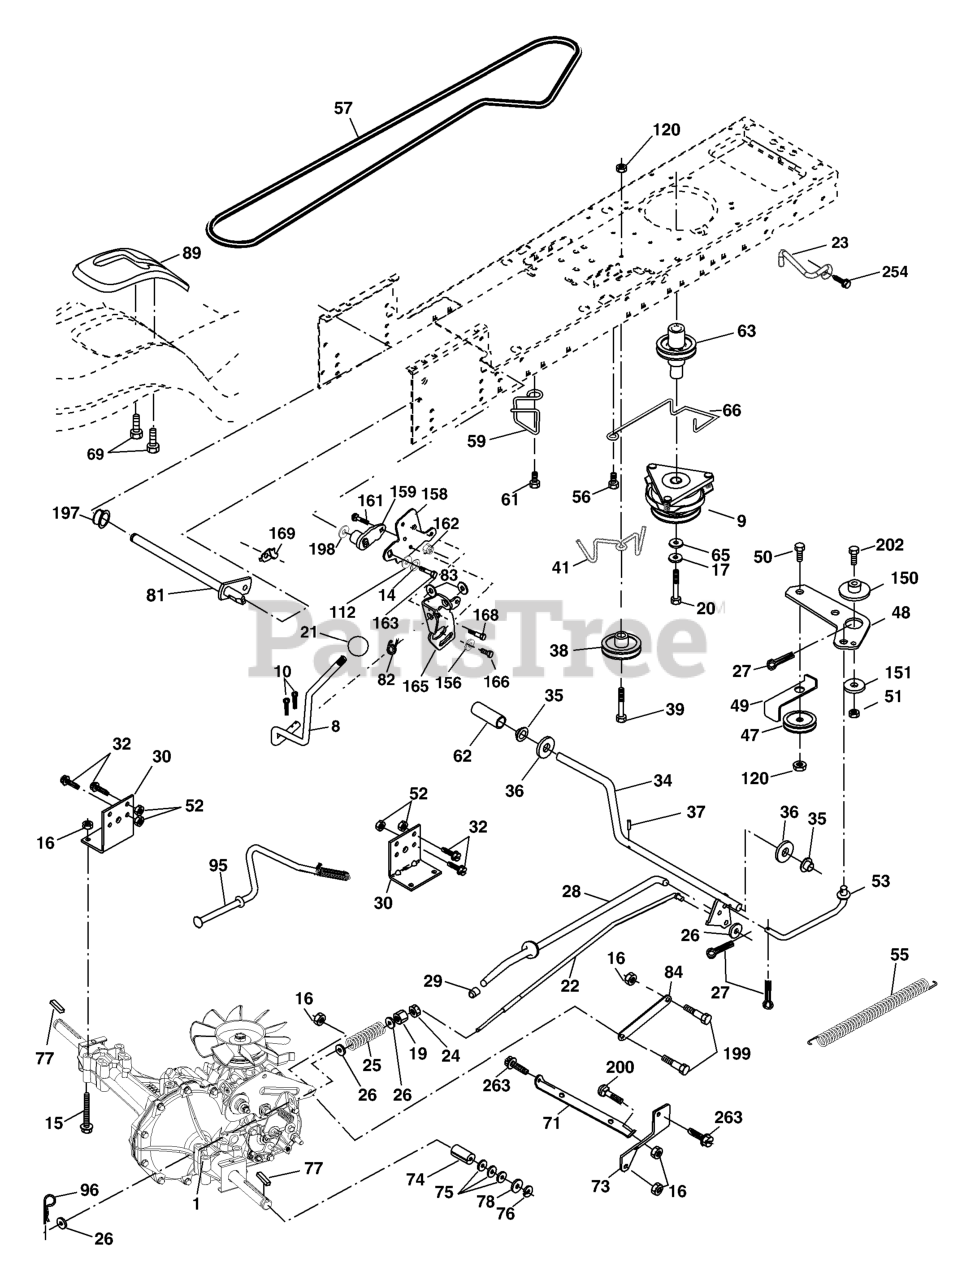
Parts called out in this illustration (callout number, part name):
8	ROD SHIFT FENDER ADJUST STLT
9	CLUTCH, ELECTRIC
10	PIN COTTER
14	LOCKWASHER
15	BOLT HEX 5/16-18 GR 5
16	NUT.71038.31-18.HEX.NYLOCK
19	NUT
20	BOLT HEX 7/16-20X4-1/4"
21	KNOB.DELUXE.(PISTOL.GRIP).BLAC
22	ROD BRAKE HYDRO
23	BRKT ASM MTNG
24	NUT
25	SPRING ROD LT
26	WASHER
27	COTTER PIN
28	ROD, PARKING BRAKE
29	PLUNGER CAP
30	BRKT, TRNSXLE MNT 20"
32	BOLT
34	SHAFT, FOOT PEDAL
35	BEARING.NYLON
36	WASHER LT
37	DRIVE PIN
38	PULLEY IDLER COMPOSITE
41	KEEPER, BELT IDLER
47	IDLER PULLEY
48	BELLCRANK, CLUTCH
49	RETAIN BELT
50	BOLT.3/8-16X1.50
52	LOCKNUT
53	LINK, CLUTCH LT
55	SPRING, RETURN LT
56	SCREW.3/8-16
57	DRIVE BELT, LTH & YTH TRACTORS
59	KEEPER, BELT CENTER
61	SCREW 3/8-16X.875
62	PEDAL COVER T
63	PULLEY, ELEC CLUTCH
65	LOCKWASHER
66	KEEPER BELT ENGINE
69	SCREW.HI-LO.CONSOLE
71	STRAP TORQUE LH HYDRO
73	STRAP TORQUE RH HYDRO
74	SPACER AXLE
77	SQUARE KEY
81	SHAFT ASM CROSS TAPERED
82	SHIFT SPRING
83	WASHER
84	LINK TRANSAXLE
89	CONSOLE SHIFT STL AUTO
95	CONTROL ASM. BYPASS HYDRO
96	RETAINER M
112	WASHER LT
116	BOLT D
120	NUT LOCK FLG 3/8-16 UNC
150	SPACER, RETAINER
151	WASHER 12/32X2X10GA
156	WASHER.SRRTD.5/16
158	BRACKET
159	RB HUB.SHIFT
161	BOLT
162	NUT.CROWNLOCK.1/4
163	BOLT
165	RP BRACKET
166	CAPSCREW.HXHD.FLG.5/16-18X.625
168	BOLT.SHOULDER.5/16-18X
169	PLATE.FASTENING.CROSS.SHAFT
197	NYLINER SNAP 5/8" ID
198	WASHER.NYL.7/8IDX.105"HYD CR
199	BOLT SHOULDER 5/16-18 UNC
200	BOLT
212	NUT
263	SCREW, 3/8-16X3/4
